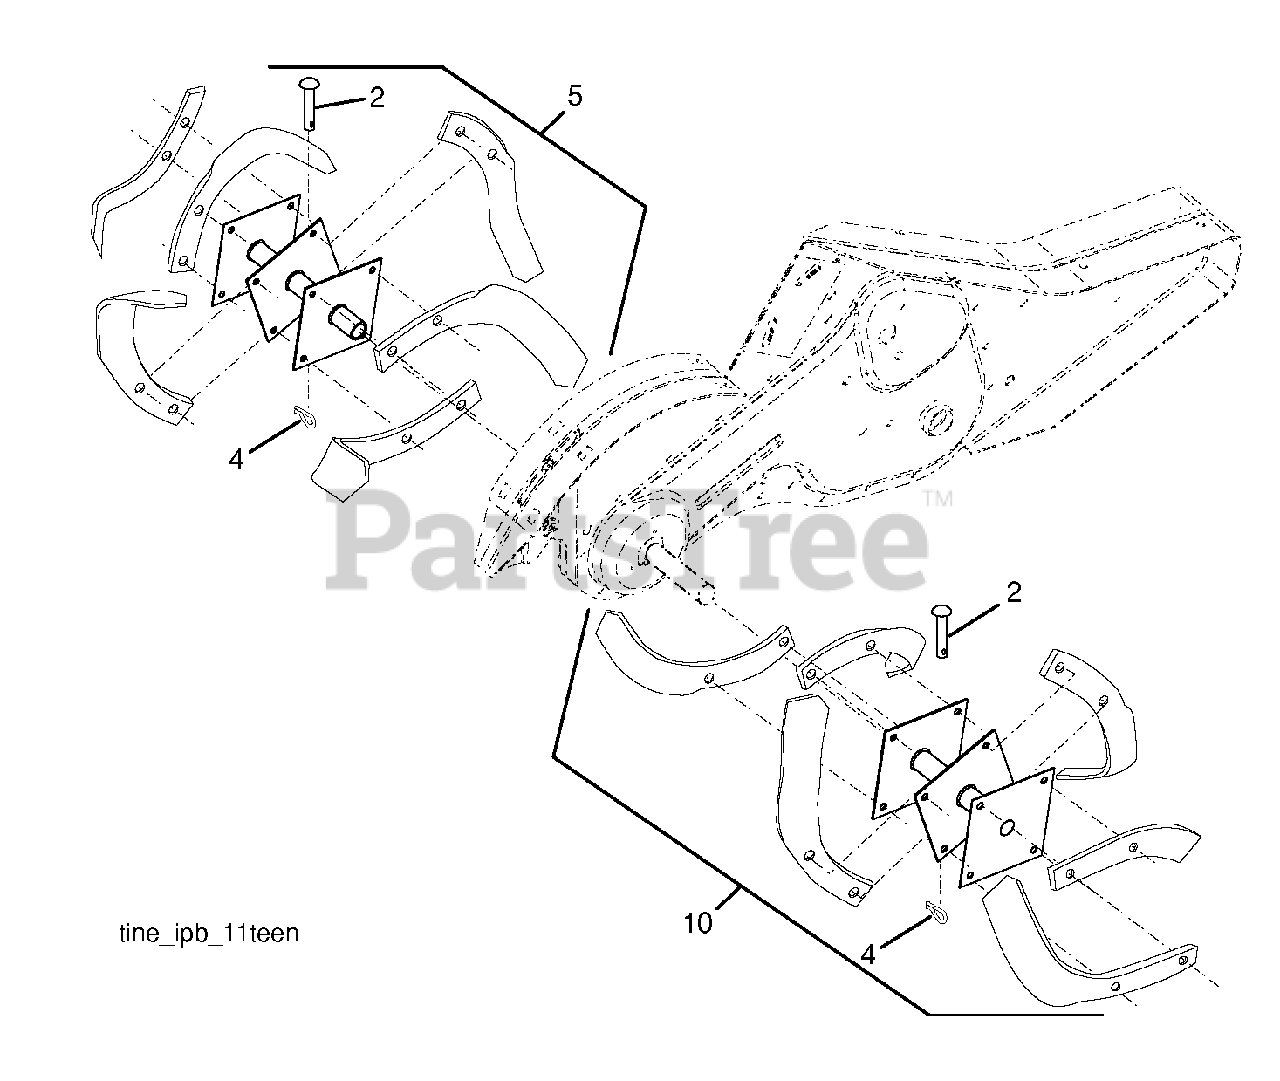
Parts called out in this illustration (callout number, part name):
2	CLEVIS PIN
4	SPRING RETAINER
5	TINE.ASM.LH.TILLER.BLACK
10	TINE.ASM.RH.PNT.479
